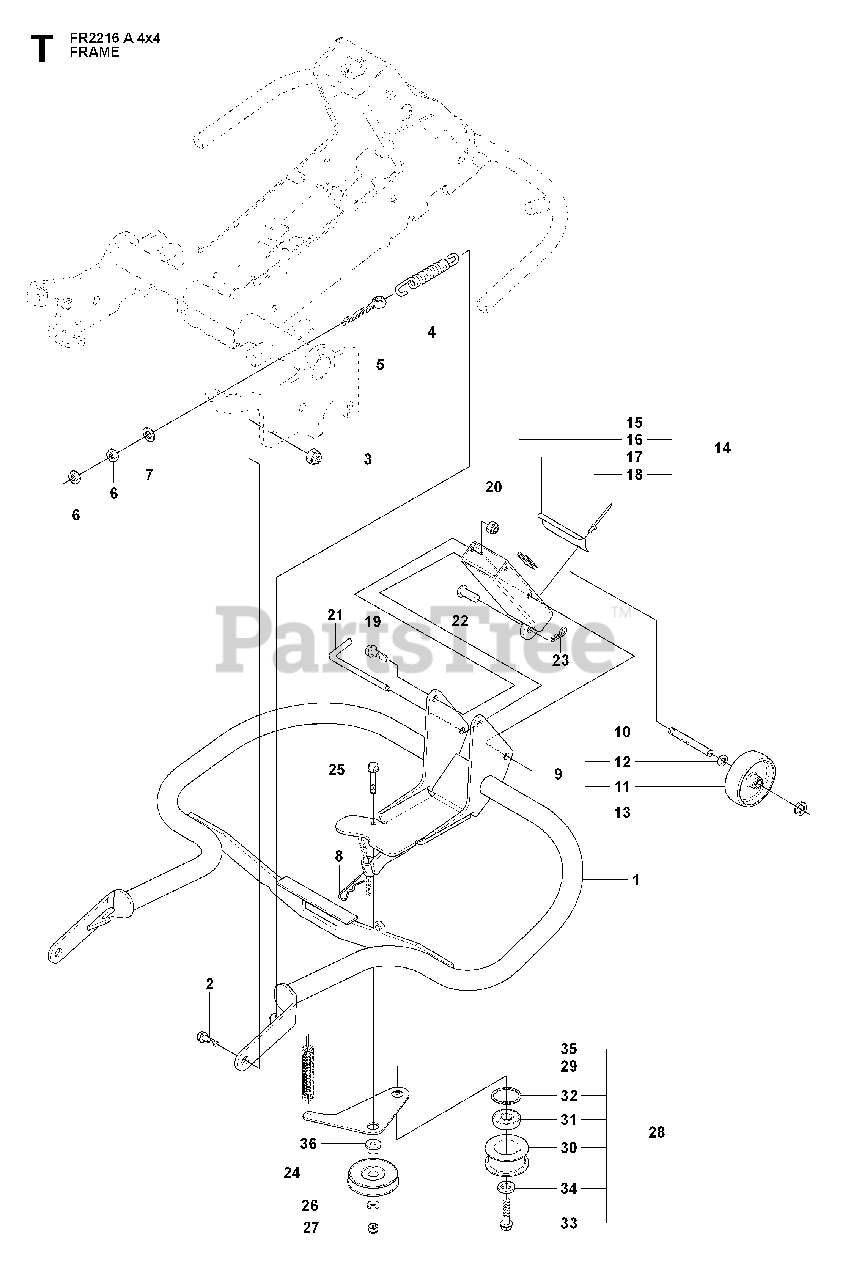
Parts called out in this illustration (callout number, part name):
7	WASHER
9	WHEEL ASSY
13	RETAINING RING
14	LINK ASSY
20	LOCKNUT M8
27	LOCKNUT M8
28	BELT TENSIONER ASSY
29	TENSIONER
30	%PULLEY
31	BALL BEARING 6004-2RS1
32	RETAINING RING
